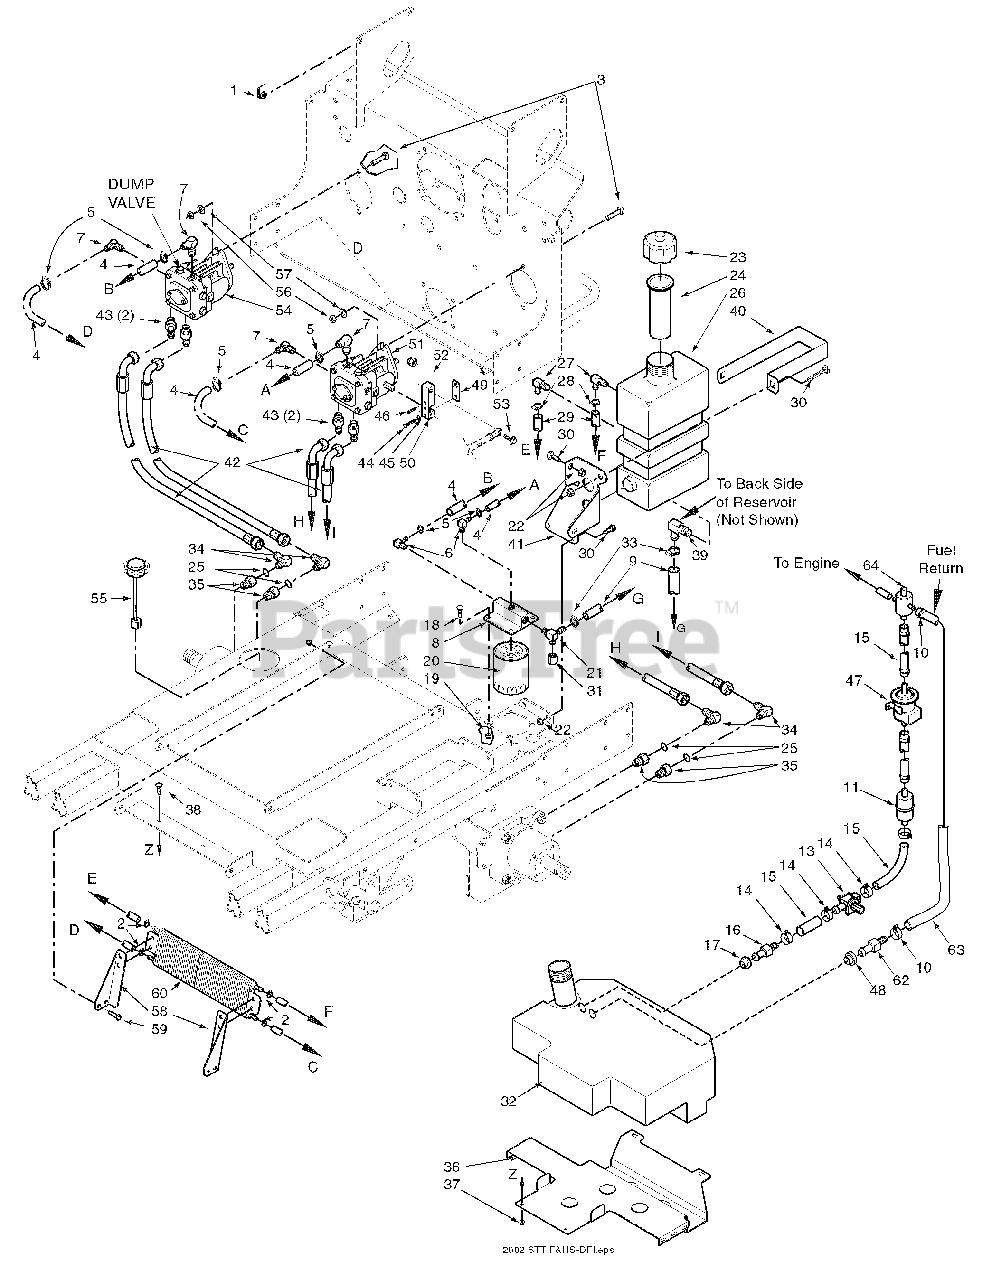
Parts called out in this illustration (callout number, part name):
1	U-Nut 1/4-20
2	Hose Clamp, 0.69 dia.
3	Bolt, Hex Head 1/4-20 x 2.0"
4	Hose, 3/8" ID Pushlock
5	Clamp, Hose 1/2"
6	Elbow, 90 Degree - 1/4 NPT x 3/8" Hose
7	Elbow, 90 Degree - 9/16 O-ring x 3/8" Hose
8	Oil Filter Base
9	Hose Assembly, 1/2" ID
10	Clamp, Fuel Hose 1/4" Hose ID
11	Fuel Filter, Kawasaki
12	Fuel Hose, 5/16" ID. Non-Perm.
13	Valve, Shutoff Kawasaki
14	Clamp, Fuel Hose
15	Fuel Hose, 5/16" ID. Non-Perm.
16	Hose Fitting w/Screen
17	Bushing
18	Bolt, Hex Head 5/16-18 x1.0" Zinc
19	Nut, Serrated Flange 5/16-18
20	Oil Filter
21	Tee, 3/4 O-ring x JIC x 1/2" Hose
22	Nut, Hex Elastic Stop 1/4-20
23	Cap, Hydraulic Tank
24	Insert, Filler Neck
25	O-Ring
26	Oil Reservoir Assembly
27	Elbow, 90 Degree .38 Hose
28	Hose Clamp, 0.69 dia.
29	Hose, 3/8" ID, Pushlock
30	Screw, Phillips Head, 1/4-20
32	Fuel Tank Assembly
33	Clamp, Hose
34	Elbow, 90 Degree, 7/8-14 THD
35	Bushing, 7/8-14 JIC x 3/4-16 O-Ring
36	Support Bracket, Fuel Tank
37	Nut, 5/16-18 Serrated Flange
38	Bolt, Carraige 1/4-20 x 3/4"
39	Elbow, 90 Degree
40	Strap, Hydraulic Tank
41	Support Bracket, Hydraulic Tank
42	Hose Assembly, Pump
43	Union, 3/4-16 JIC x 3/4-16 O-ring
44	Bolt, Hex Head, 1/4-20 x 1-14"
45	Lockwasher, 1/4" Spring
46	Roll Pin, Spring 3/16 x 3/4"
48	Bushing
49	Clamp Plate, Pump Control
50	Block, Pump Control
51	Pump, Left Hand, BDP-16A
52	Nut, Hex, Elastic Stop 3/8-16
53	Bolt, Hex Head, 3/8-16 x 1-1/4
54	Pump, Right Hand, BDP 16A
55	Cap, Fuel Tank W/Gauge
56	Nut, Hex Elastic Stop 3/8-16
57	Flatwasher, 3/8" Grade 8
58	Mounting Bracket - LH, Oil Cooler
59	Bolt, Hex Head 5/16-18 x 3/4"
60	Cooler, Oil
61	Clamp, .69 Dia.
62	Fitting, Hose
63	Hose, 1/4" Fuel Line Non-Perm.
64	Regulator Assembly, Fuel Pressure
